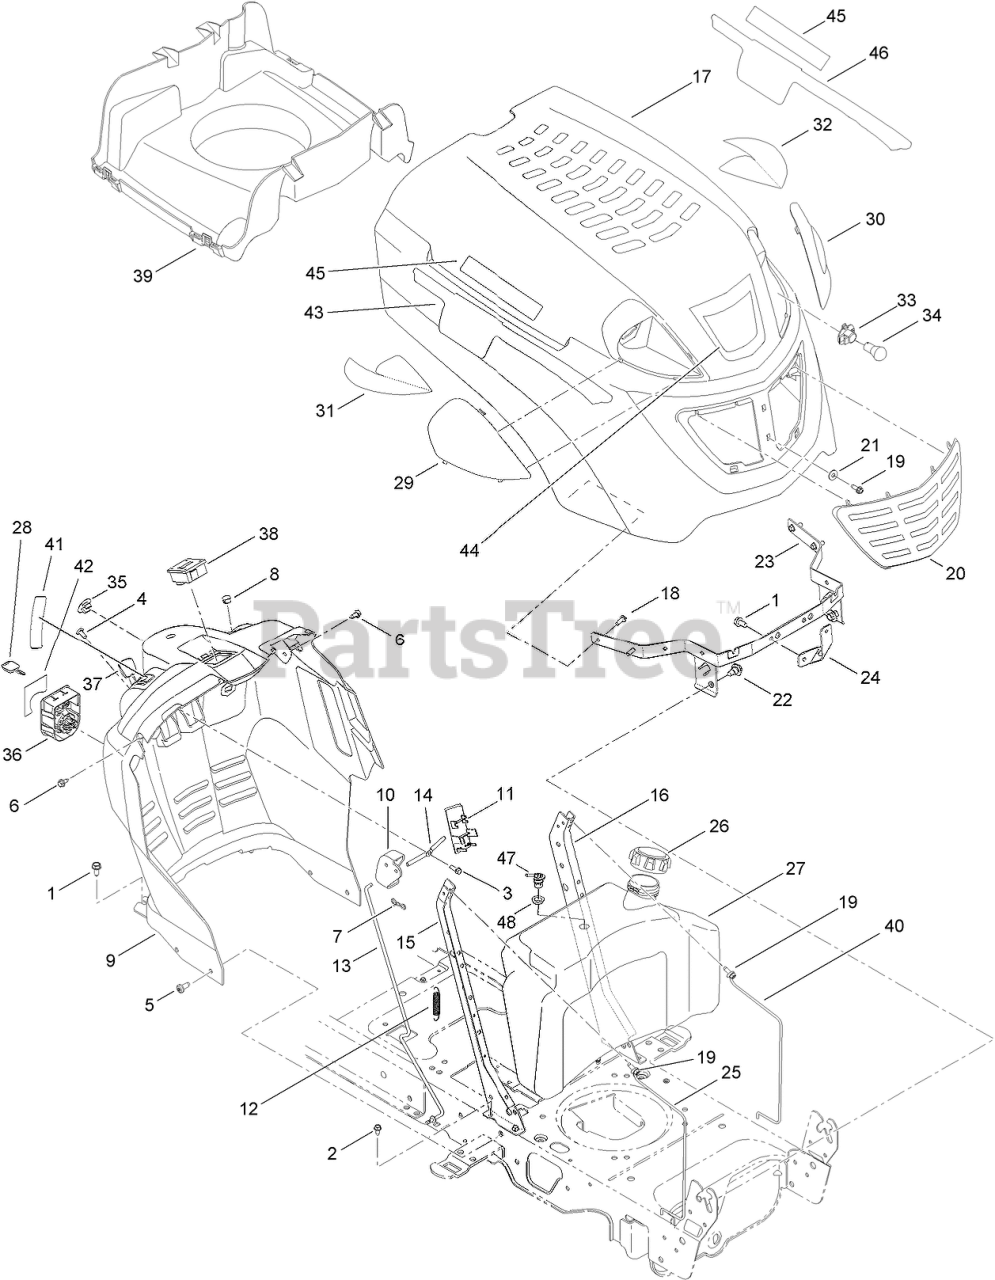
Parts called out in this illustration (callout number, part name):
1	SCREW-TAP
2	SCREW-HWHTF
3	SCREW-TAP
4	SCREW-TAP
5	SCREW-TAP
6	SCREW-HWH
7	PIN-COTTER
8	CAP-PLUG, HOLE
9	DASH-MANUAL, PTO
10	LEVER-DASH
11	COVER-CRUISE
12	SPRING-EXTENSION
13	ROD-LATCH
14	ROD-LEVER, BENT
15	SUPPORT-DASH, PLATE (RH)
16	SUPPORT-DASH, PLATE (LH)
19	SCREW-TAP
21	WASHER-FLAT
22	BOLT-SHOULDER, TAP
23	BRACKET-PIVOT
24	BRACKET-SUPPORT, HOOD
25	ROD-SUPPORT
26	CAP-FUEL
27	TANK-FUEL
28	KEY-IGNITION
29	LENS-RH
30	LENS-LH
31	REFLECTOR-RH
32	REFLECTOR-LH
33	SOCKET-HEADLIGHT
34	LAMP-12V, MINIATURE
35	PLUG-CHOKE
36	MODULE-SWITCH, IGNITION
37	CABLE-THROTTLE/CHOKE
38	METER-HOUR
39	PLENIUM-HOOD
40	ROD-SUPPORT, LH TANK
41	DECAL-THROTTLE
42	DECAL-SWITCH, IGNITION
43	DECAL-HOOD, RIGHT SIDE
44	DECAL-HOOD
46	DECAL-HOOD, LEFT SIDE
47	Valve-Rollover, Grommet
48	Grommet-Rubber
